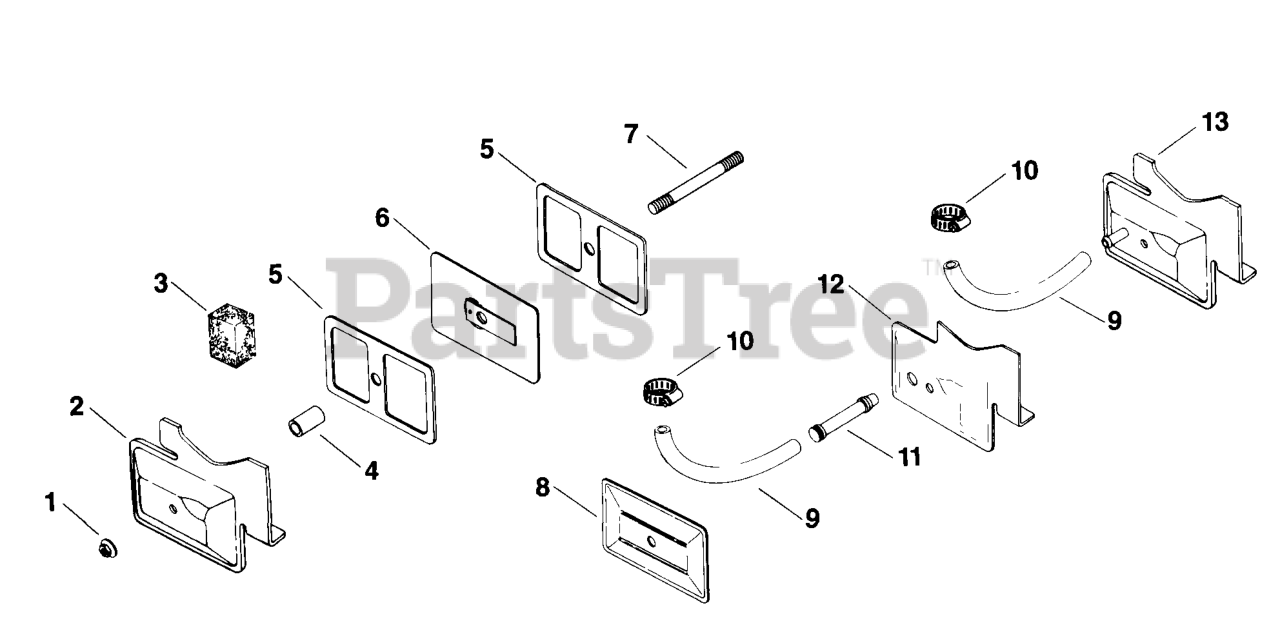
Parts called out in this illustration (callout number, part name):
1	PALNUT, 1/4-20
2	COVER ASSEMBLY, VALVE
3	FILTER, BREATHER
4	SEAL, BREATHER
6	BREATHER - DISCONTINUED
7	STUD,1/4-20x3-9/16"-DISCONTINUED
